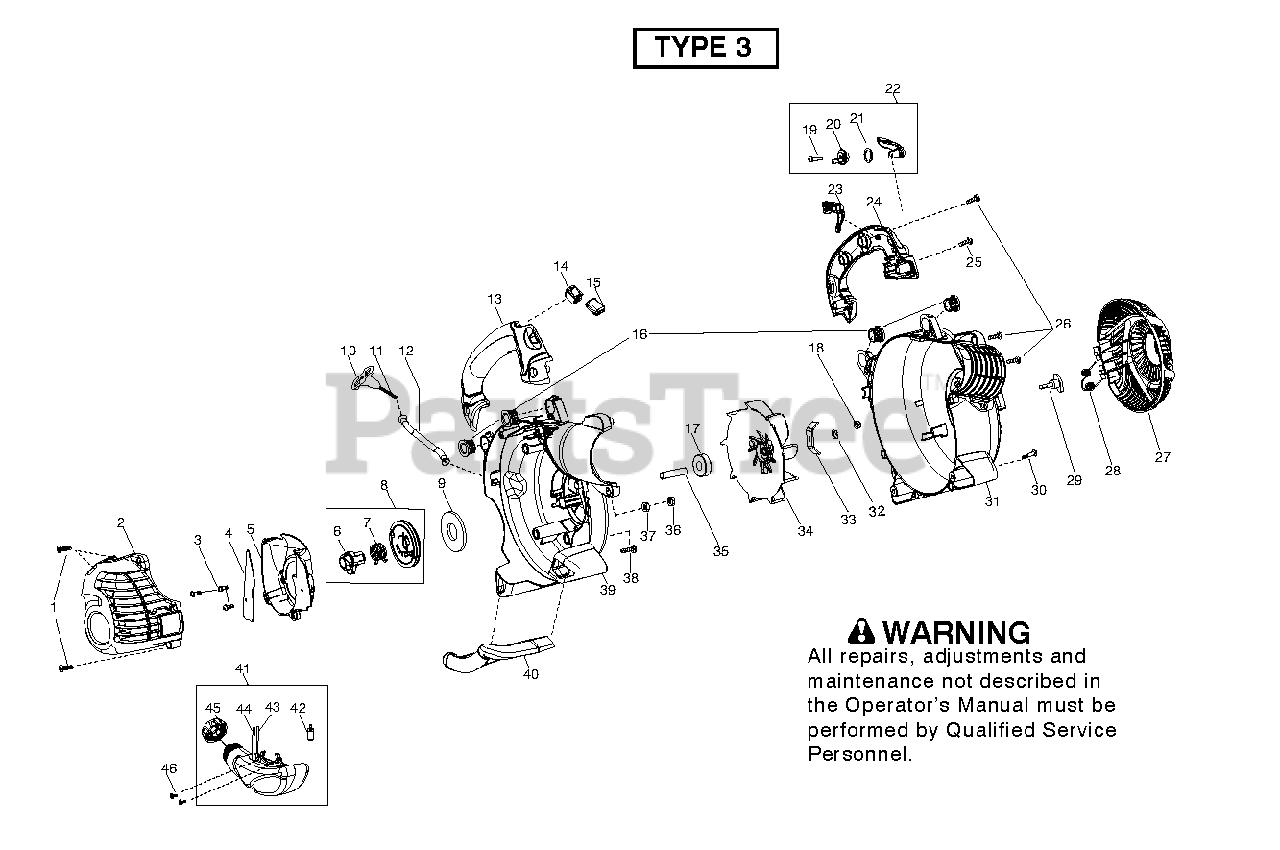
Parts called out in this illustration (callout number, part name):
2	ASSY COVER ENGINE S
4	SHIELD BAFFLE
6	Pulley Hub, Si Sm
8	KIT STARTER PULLEY
9	SPRING STARTER SA
11	Starter Rope Kit
12	TUBE STARTER ROPE
13	Handle with Soft Grip, RT
14	KIT SWITCH
15	PROTECTOR, SWITCH
20	RATCHET CRUISE CONTROL
22	TRIGGER THROTTLE CONTROL
25	SCREW #10 PLASTITE 1.362
27	DOOR VAC BLACK
28	SPRING VAC DOOR
31	ASSY SCROLL AV LH SRS BLK
34	ASSY IMPELLAR HUB
35	SPACER FLYWHEEL
39	ASSY SCROLL BEARING BLACK
41	Fuel Tank Assembly, Non Low Perm St
42	FUEL PICK-UP ASSY
45	ASSY FUEL CAP W/RETAINER
46	SCREW FUEL TANK RETAINER
